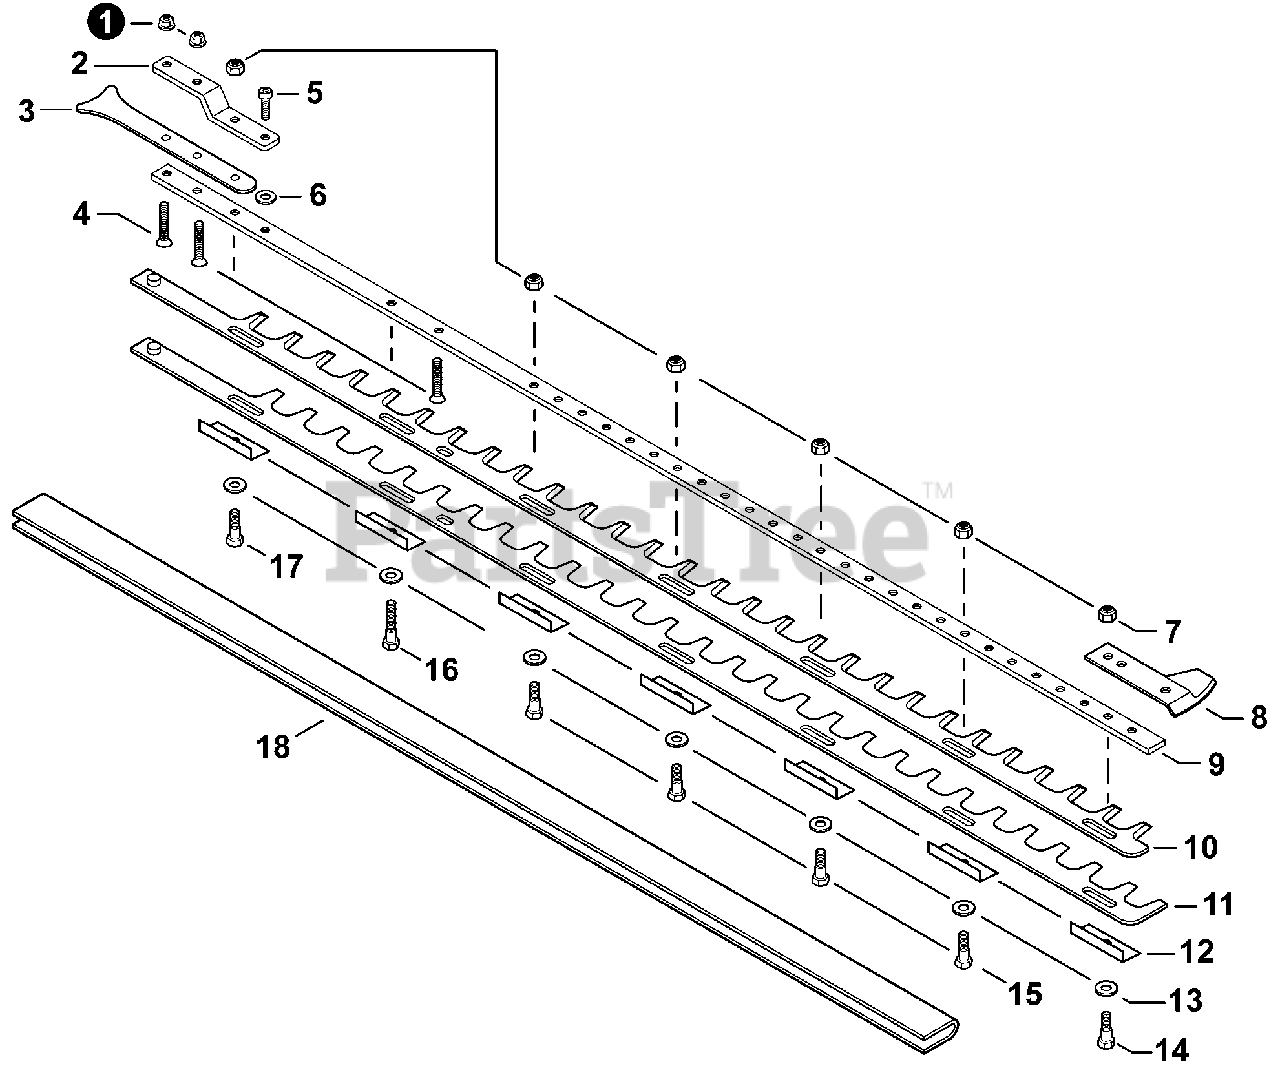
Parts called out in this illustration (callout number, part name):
1	NUT, FLANGE M6
2	BRACKET, BLADE
3	PLATE, EYE
4	BOLT 6×30
5	BOLT 6x12
8	GUARD, TIP
9	SUPPORT, BLADE 40"
10	BLADE, UPPER 40"
11	BLADE, LOWER 40"
12	GUIDE, BLADE
14	BOLT 6×24
15	BOLT 6×22
16	BOLT 6×40
17	BOLT 6×35
18	SCABBARD
